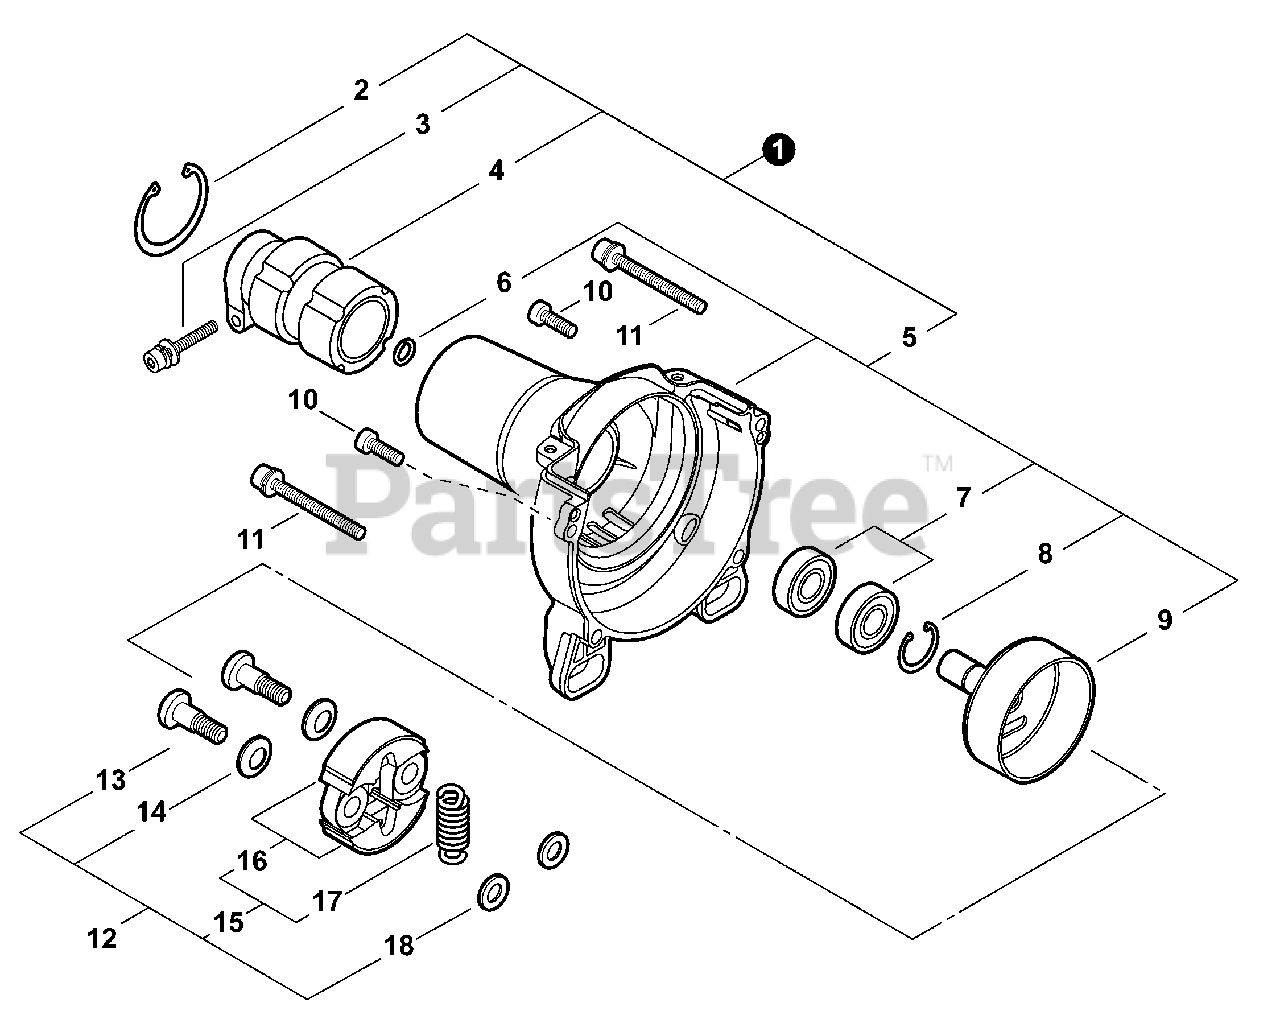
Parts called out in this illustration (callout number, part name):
1	COVER ASSY, FAN
2	RING, SNAP 42
3	BOLT M5×28
4	CUSHION, AV
5	COVER KIT, FAN
6	RING, SNAP 12
7	BEARING, BALL 6001 DDU C3
8	RING, SNAP 28
9	DRUM, CLUTCH
10	BOLT M5×16
11	BOLT M5×45
12	CLUTCH ASSY
13	BOLT, CLUTCH
14	WASHER, SPRING
15	SHOE ASSY, CLUTCH
16	SHOE, CLUTCH
17	SPRING, CLUTCH
18	WASHER 6MM
